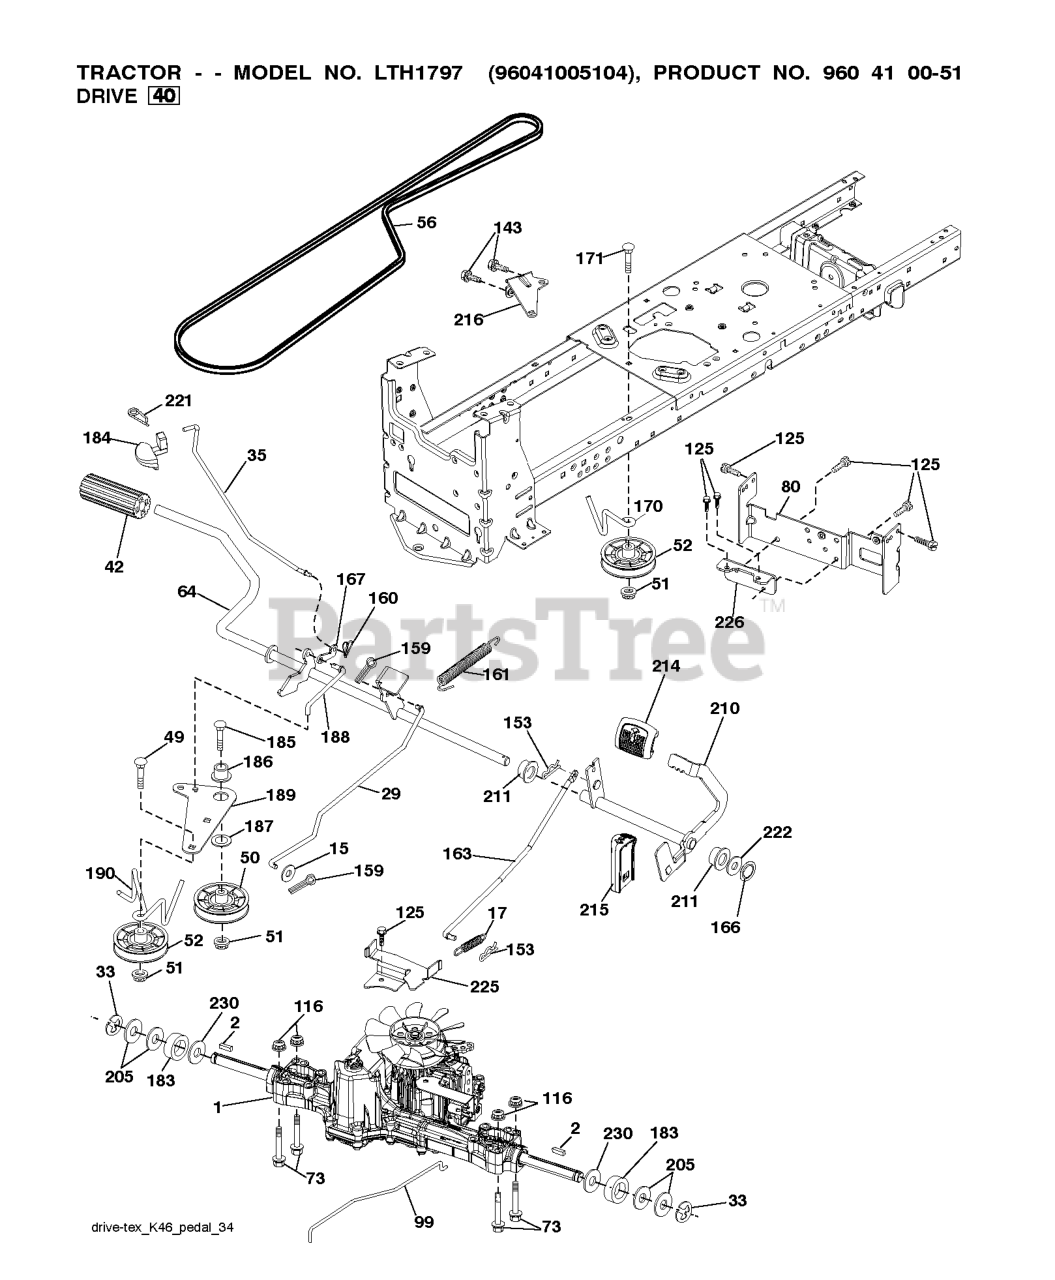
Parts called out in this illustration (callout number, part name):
2	SQUARE KEY
15	WASHER
17	SPRING.BRAKE.K46.GREEN
29	ROD.BRAKE.K46
35	ROD.CNTRL.PARK.PREDATOR.LT.TEX
42	PEDAL COVER T
50	IDLER.FLAT.910.OFFSET
51	NUT LOCK FLG 3/8-16 UNC
52	IDLER.V-GROOVE.910.OFFSET
56	V-BELT.MOWER.92.40.42/K46
64	SHAFT.ASM.PEDAL.BRK.CNTR
73	BOLT HEX 5/16-18 GR 5
80	STRAP TORQUE
99	ROD.SPRING.BYPASS.K46.LT.Z
116	NUT LOCK HEX FLANGE 5/16-18
125	SCREW
143	Screw 5/16-18 x 1/2 Hex, Self Tapping 5/16-18 x 1/2
153	RETAINER M
159	COTTER PIN
160	RETAINER CLIP
161	SPRING, RETURN LT
163	ROD.CONTROL.PEDAL.K46
166	NUT.PUSH.625
167	LATCH.BRAKE.SPRING
170	KEEPER.V-IDLER.CENTER.
183	SPACER AXLE
184	HANDLE PARKING BRAKE
186	SPACER.RETAINER
187	WASHER 12/32X2X10GA
188	RP.LINK.CLUTCH.GROUND.DRIVE
189	BELLCRANK.GROUND.DRIVE.TEX.
190	KEEPER.BELLCRANK.DRIVE
210	ROCKER.ASM.PEDAL.CONTR
211	BEARING.NYLON
214	PEDAL.FORWARD.PAD.TEX
215	PEDAL.REVERSE.TEX.GT.4
216	BRACKET.PULLEY.IDLER.W/TEX
221	RETAINER.SPRING.CLIP.H
222	WASHER 21/32 X 1-1/4 X 10 GA.
225	KEEPER.BELT.TRANSAXLE.K46
226	BRACKET.MOUNT.TORQUE.K46.TLT
230	WASHER.HARDENED
